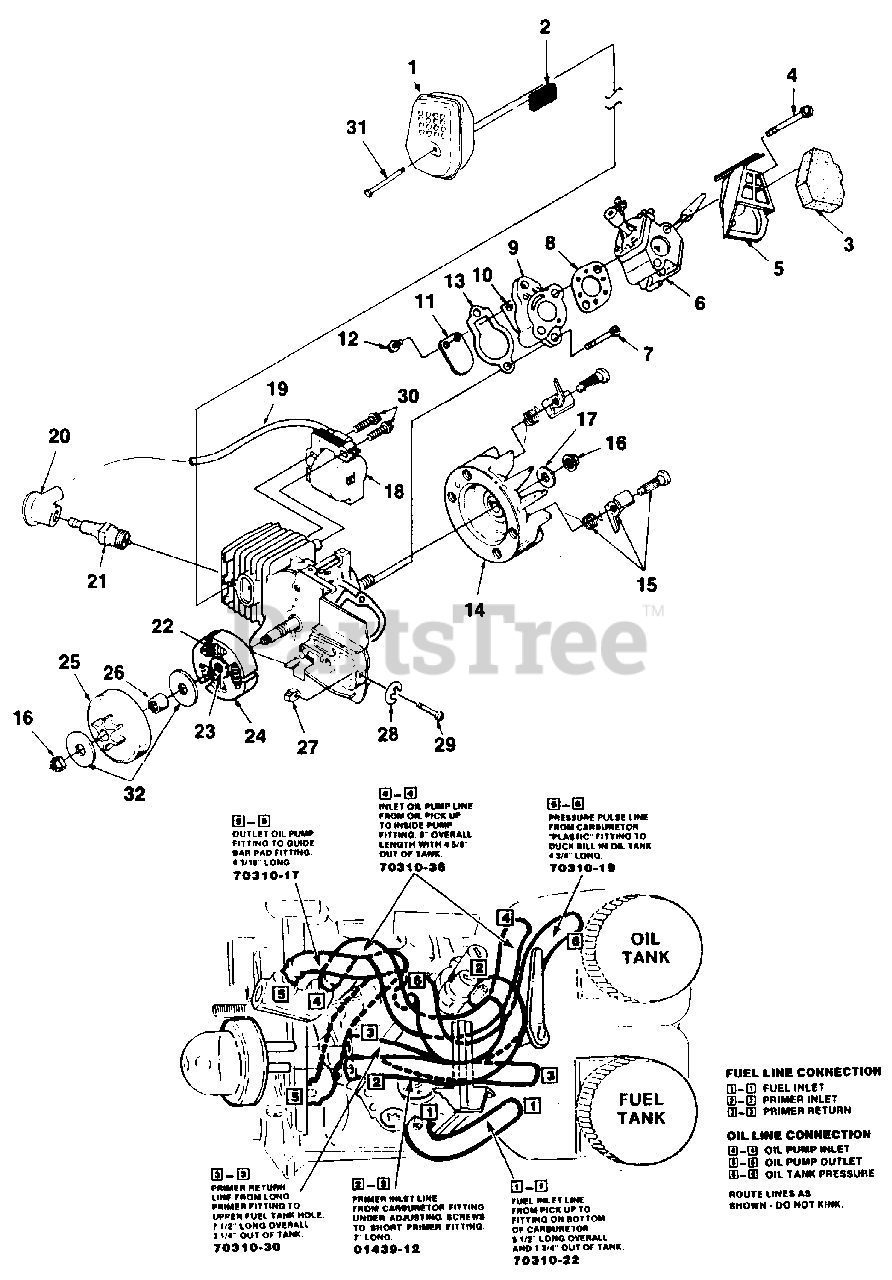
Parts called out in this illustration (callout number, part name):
1	MUFFLER
2	SCREEN- Spark arrestor
3	FILTER- Air (10-24 x 1 7/8")
4	SCREW- Shoulder plastite (#10-24 x 1 3/4")
5	BOX- Air filter
6	CARBURETOR & OIL PUMP ASSY.
7	SCREW- Torx taptite, thd. forming (10-24 x 1")
8	GASKET- Carburetor
9	HEAT DAM
10	REED
11	STOP- Reed
12	SCREW- Hex Taptite (4-40 x 3/9)
13	GASKET- Intake manifold
14	ROTOR & STARTER PAWL
15	KIT- Starter pawl
16	NUT- (5/16-24)
17	WASHER- (5/16")
19	LEAD- Hi-Tension
20	TERMINAL
21	SPARK PLUG (Champion DJ7Y)
22	SPRING- Clutch
23	SPIDER- Clutch
24	SHOE- Clutch
25	SPROCKET & DRUM
26	BEARING
27	PIN- Adjusting
28	SCREW & E-RING KIT
29	E-RING
30	SCREW Machine hex sems
31	SCREW- Machine hex sems (10-24 x 1 7/8")
32	WASHER- Thrust
